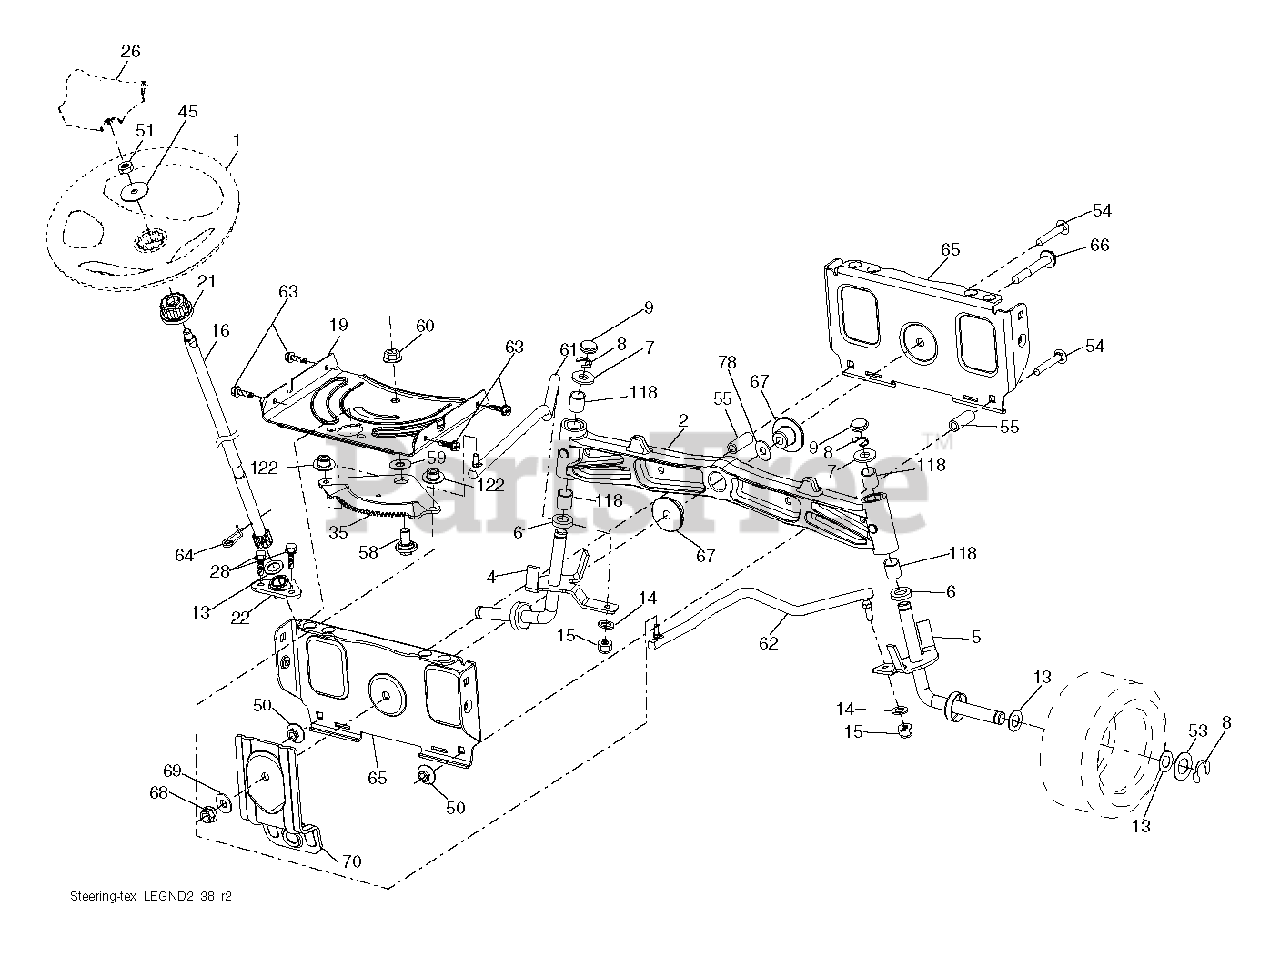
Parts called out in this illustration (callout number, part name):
1	WHEEL.STEER.HUSQ.SR.498.OVMLD
2	AXLE.SVC.ASM CAST IRON.TEX
4	SPINDLE.WELDED.LH.16"TEX
5	SPINDLE.WELDED.RH.16"TEX
6	THRUST WASHER
9	CAP.SPINDLE.BLACK
14	WASHER, LOCK 3/8
15	NUT CROWNLOCK 3/8-24
16	SHAFT.STEER.STEALTH.DD
19	PLATE.STEER.DDL.NLT/NG
21	ADAPTER, WHEEL STNG..
22	STEERING.SUPT.LOWER.
26	INSERT.CAP.WHL.STRG.HUSQ.PREM
28	SCREW, 3/8-16X3/4
35	GEAR.SECTOR.PLATE.DDL.
45	WASHER 9/16"ID, 2 3/8"OD
50	NUT LOCK FLG 3/8-16 UNC
51	NUT.HEX.1/2-20
53	WASHER.HARDENED
55	SPACER.BRACE.AXLE
58	BOLT.SHOULDER.SECTOR.P
59	WASHER.THURST.SECTOR.S
60	NUT FLANGE LOCK 5/8-11
61	DRAGLINK.LH.BALLSTUD.D
62	DRAGLINK.RH.BALLSTUD.D
63	SCREW
64	RETAINER.CLIP.SPRING.S
65	BRACE.AXLE.FRONT.NLT/N
66	BOLT HEX FGHD 7/16-14 X 3 SERR
67	BUSHING.PM.FRONT AXLE
68	NUT.LOCK.FLANGE.7/16
69	WASHER.1.5X.505X.118
70	BRKT.DECK.SUSPENSION.F
78	THRUST WASHER
118	BUSHING, AXLE CAST
122	CAP.GEAR.SECTOR.TEX
